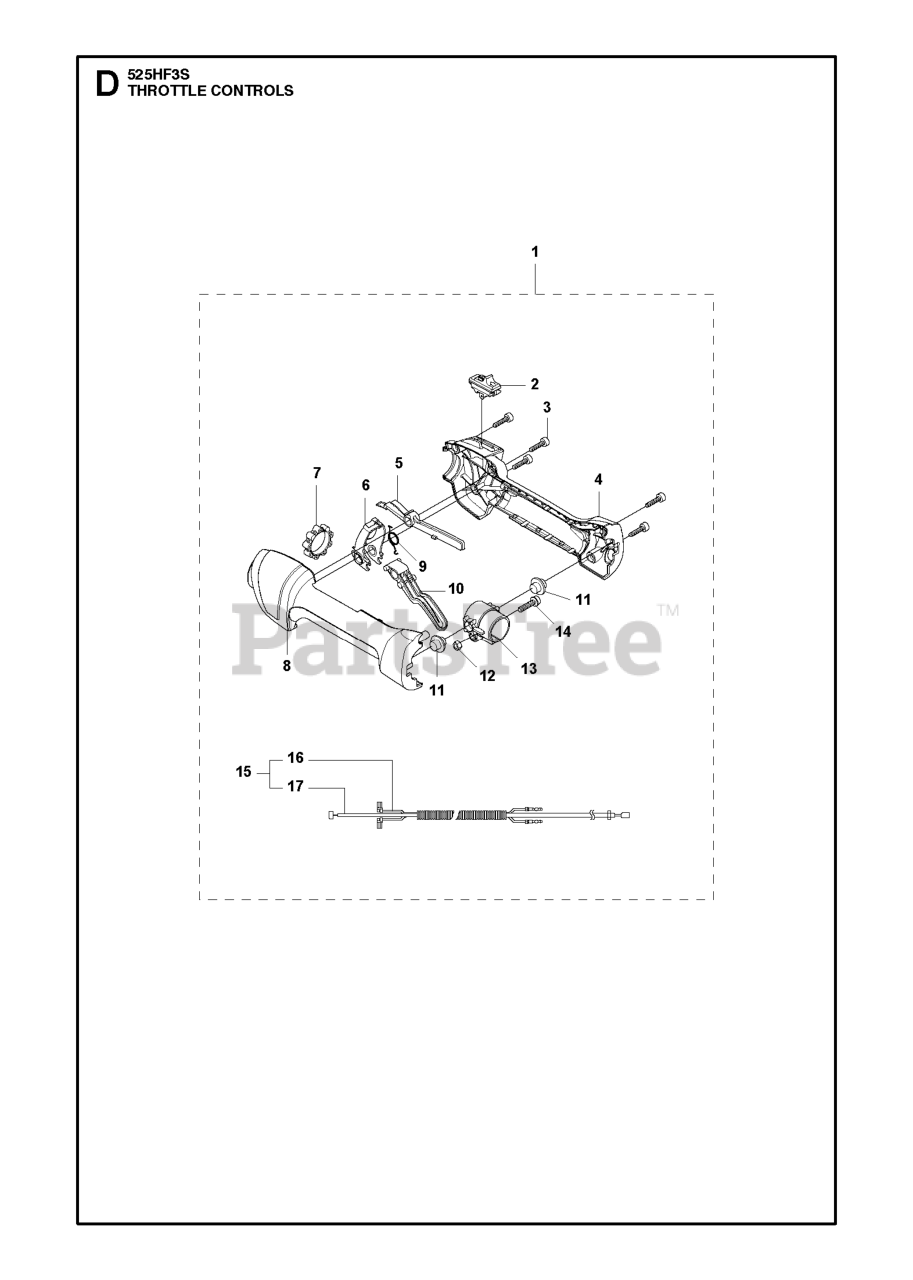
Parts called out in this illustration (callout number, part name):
1	THROTTLE CONTROL
1	ASSY THROTTLE CONTROL
2	STOP BUTTON
2	DRAWBAR
3	SCREW 3/8-16X3/4
5	THROTTLE LOCK
5	BUMPER DASH
6	PLATE
7	VIBRATION DAMPER
8	CLIP,INSULATOR
9	RETURN SPRING
10	THROTTLE TRIGGER
10	BOLT D
11	DAMPER
11	VIBRATION ABSORBER
11	PANEL.DASH.LH.LTX
13	HOLDER
13	RETAINER
13	PANEL ASM, DASH RH
15	WIRING ASSY
15	Screw, Machine, Truss Head 5/16-18 UNC x 3/4
16	SHORT CIRCUIT CABLE
16	NUT
17	THROTTLE CABLE
17	HOOD
18	BUMPER.HOOD.TEX.HUSQVARNA
25	WASHER
26	NUT
28	RP GRILLE/LENS ASM.
30	CONSOLE.CRD.AUTO.GRY
31	BRACKET SUPPORT FENDER
33	FOOTREST PNT LH
34	FOOTREST PNT RH
37	Screw 5/16-18 x 1/2 Hex, Self Tapping 5/16-18 x 1/2
38	BRACKET ASM PIVOT MOWER REAR
39	BRACKET PIVOT
69	SCREW.HI-LO.CONSOLE
89	CONSOLE.CRD.AUTO.GREY.2005
145	ROD.PIVOT.HOOD
162	BRACKET
163	BRACKET EXTEN CHASSIS RH CRD
165	RP.COVER.BATTERY.CRD.GREY
172	WASHER
175	DOOR TRAP
179	ROD PIVOT FBI
184	BRACKET.ACTUATOR.BAGGER.SRD
186	LATCH ASSY
187	WELDNUT
189	LOCKWASHER #10
190	SCREW
207	SCREW, 5/16-18 X 1/2
208	SCREW 3/8-16X1/2
209	SCREW, 3/8-16X3/4
212	INSERT REFLECTIVE
213	SKIRT SIDE LH
214	SKIRT SIDE RH
216	SCREW HEXWSHR 1/4-20X3/4
256	COVER FENDER CRD
258	LENS.HUSQVARNA LT.RH
259	LENS.HUSQVARNA LT.LH
265	SEALING
266	SEALING
272	VENT SIDE HOOD LH
273	VENT SIDE HOOD RH
278	SCREW.#10 X 0.750.BOS
295	VENT TOP HOOD
296	TRIM
297	CLIP.RETAINER.TINNER.
298	NUT PUSH M
299	RP LOGO
305	INSERT REFLECTIVE
306	INSERT.REFLECTIVE.RH.
